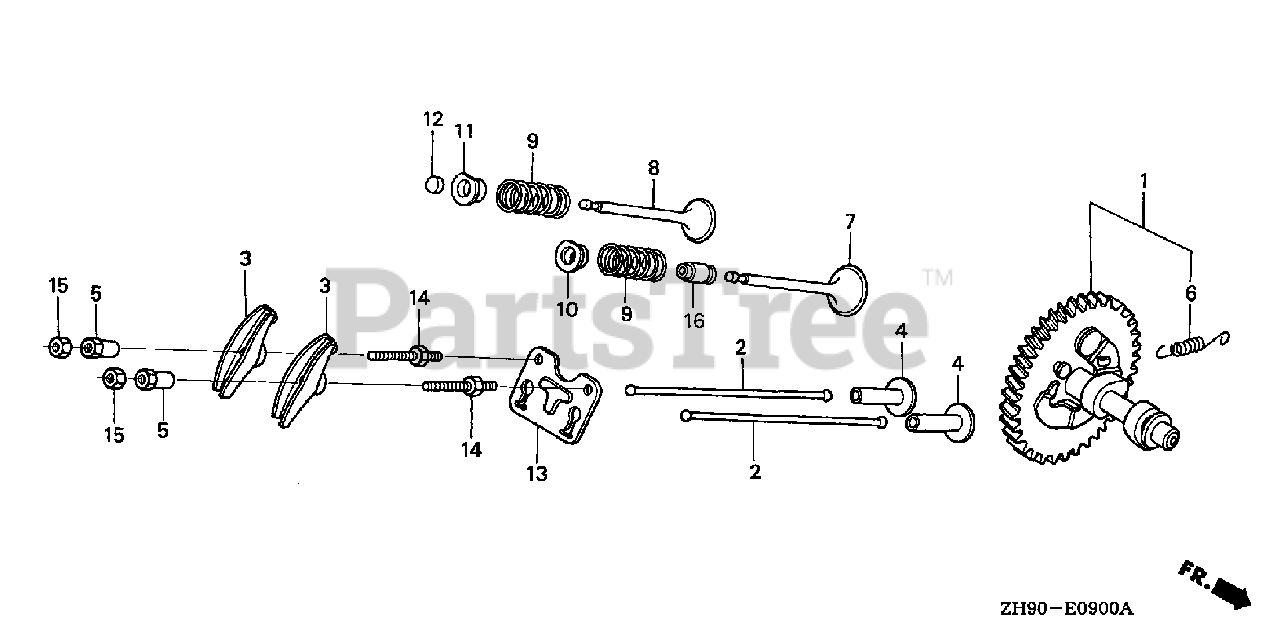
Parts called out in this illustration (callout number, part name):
1	CAMSHAFT ASSY.
2	ROD, PUSH
3	ARM, VALVE ROCKER
4	LIFTER, VALVE
5	PIVOT, ROCKER ARM
6	SPRING, WEIGHT RETURN
7	VALVE, IN.
8	VALVE, EX.
9	SPRING, VALVE
10	RETAINER, IN. VALVE SPRING
11	RETAINER, EX. VALVE SPRING
12	ROTATOR, VALVE
13	PLATE, PUSH ROD GUIDE
14	BOLT, PIVOT (8MM)
15	NUT, PIVOT ADJ.
16	SEAL, VALVE STEM
